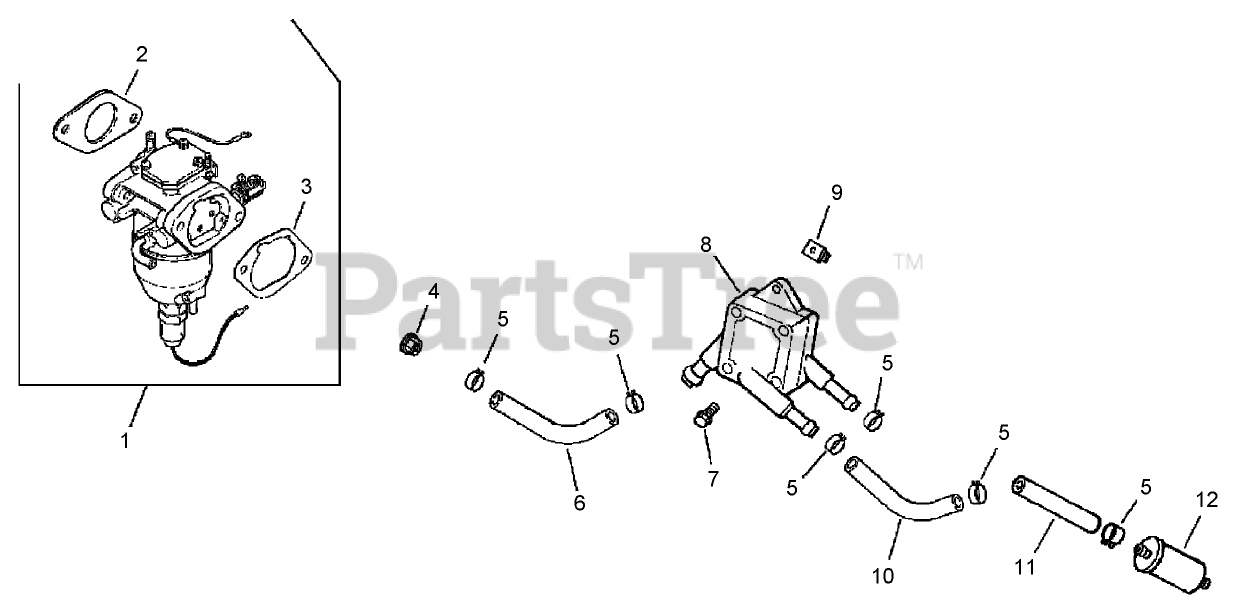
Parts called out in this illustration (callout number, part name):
1	Kit, carburetor w/gaskets
2	Gasket-carburetor
3	GASKET-BASE, AIR CLEANER
4	NUT-FLANGE (M6X1.0)
5	CLAMP-HOSE, SPRING (1/2)
6	Line, fuel 6-1/4
7	SCREW-TAP (M6X1.7X18)
8	PUMP-FUEL
9	Nut-Plastic
10	Line, fuel 10-1/2
11	Line, fuel 13
12	Filter-Fuel
